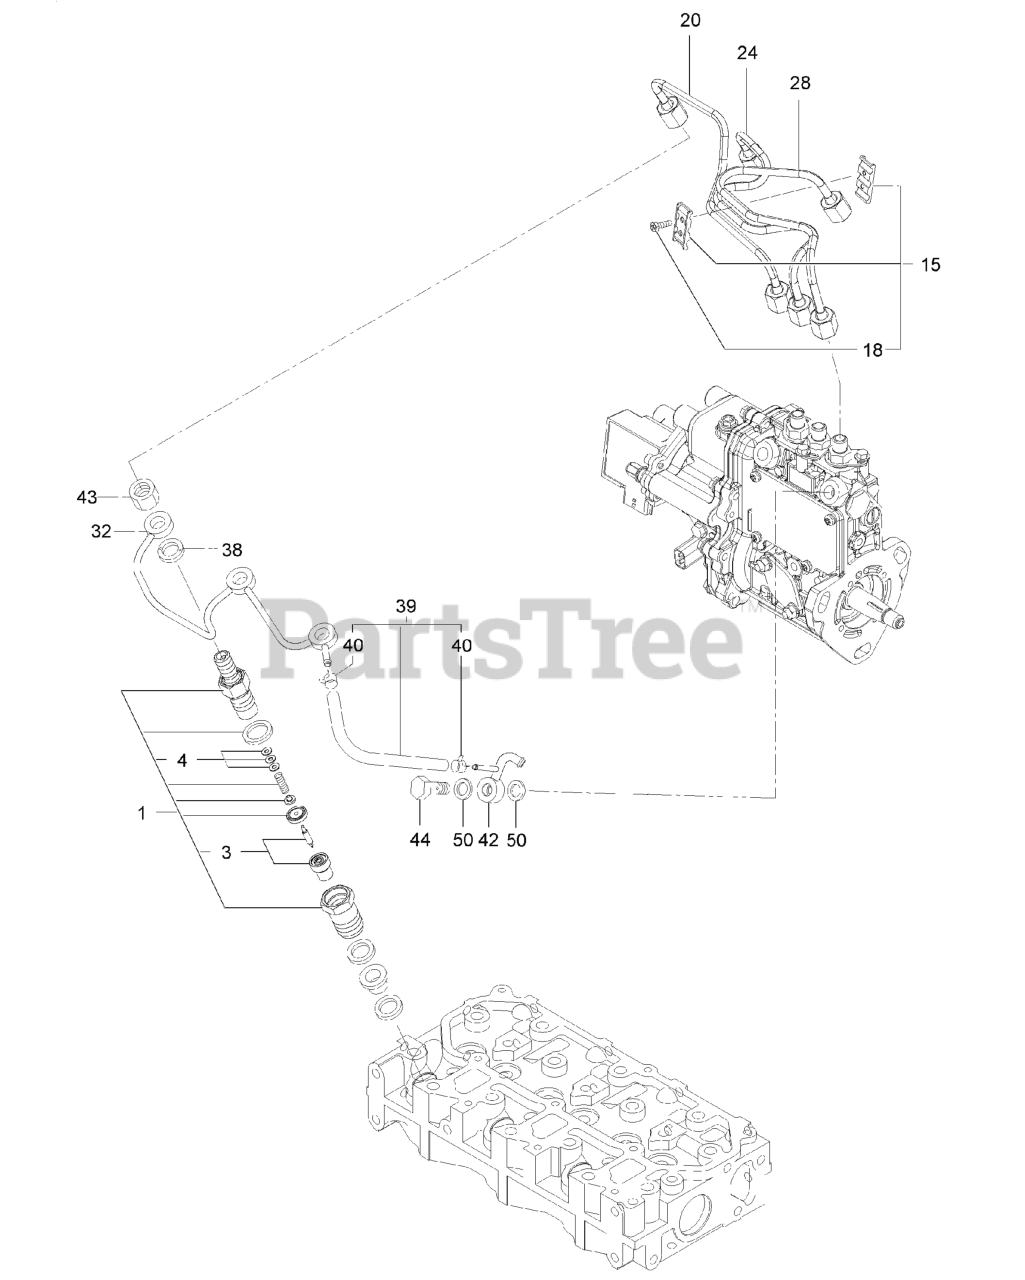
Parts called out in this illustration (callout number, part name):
1	NOZZLE ASM
3	NOZZLE ASM
4	SHIM SET-ADJUSTING
15	RETAINER-PIPE
20	PIPE ASM
24	PIPE ASM
28	PIPE ASM
32	PIPE ASM
39	HOSE ASM
40	CLAMP-HOSE
42	JOINT-OVER FLOW
43	NUT-NOZZLE
44	VALVE ASM-CHECK
50	WASHER-SEAL
